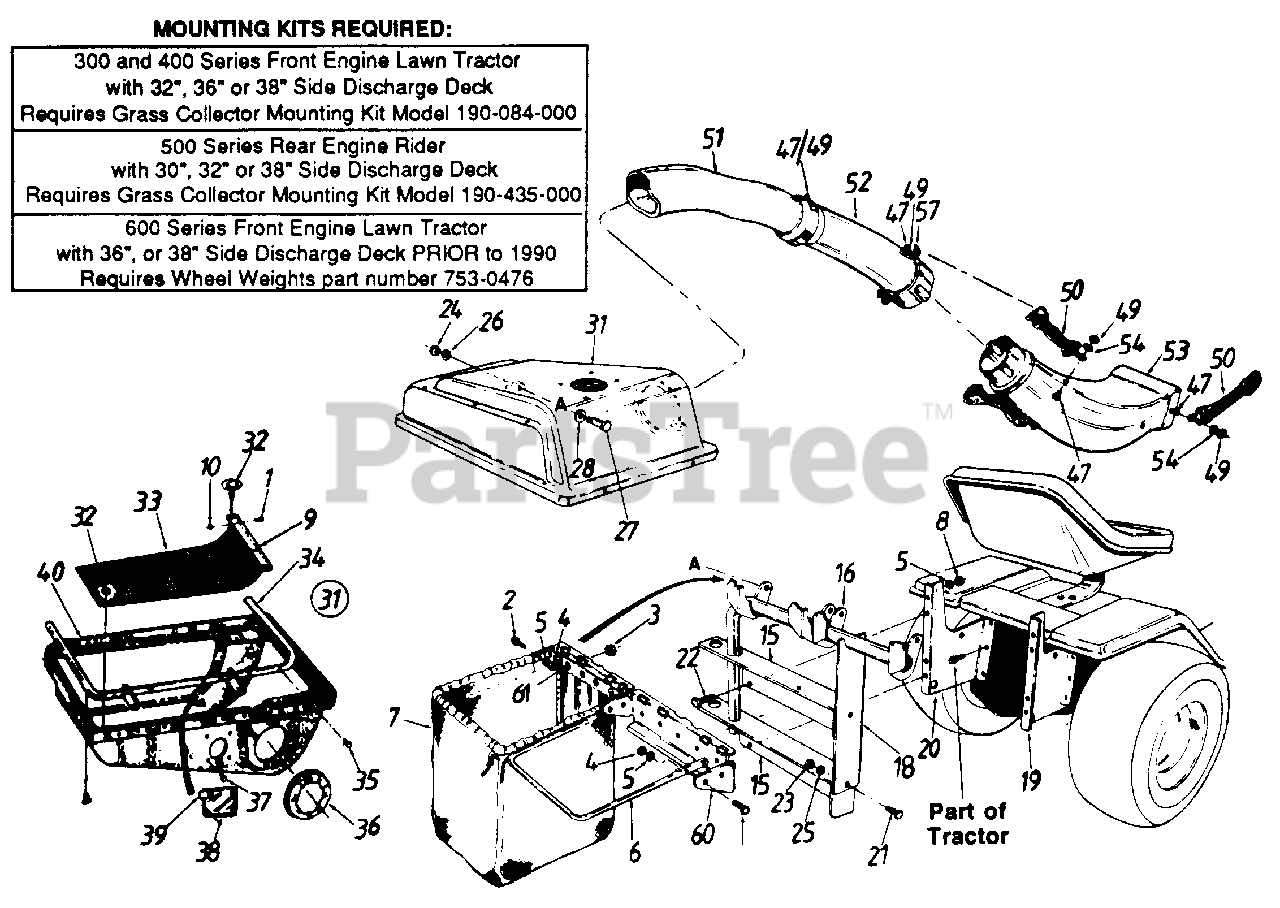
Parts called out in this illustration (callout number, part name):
1	Pop Rivet .188 Dia.
2	Hex Bolt 1/4-28 x .75"
3	Hex Sems Nut #10-24 Thd.
4	Hex Nut 1/428 Thd.
5	L-Wash. 1/4" I.D.
7	Grass Catcher Bag
8	Hex Nut 1/4-20 Thd.
9	Screen Mtg. Brkt.
10	Flat Wash. 1/4" I.D.
16	Catcher Support Tube Ass'y.
18	Catcher Latch and Support Brkt.
22	Hex Bolt 1/4-20 x .62" Lg. Grade 5
23	Hex Nut 5/16-18 Thd.
24	Hex Nut 3/8-16 Thd.
25	L-Wash. 5/16" I.D.
26	L-Wash. 3/8" I.D.
27	Shld. Bolt 3/8-16 x 50" Dia.
28	Bell-Wash. .505" I.D. x .0" O.D.
31	Grass Catcher Cover Ass'y.
32	Twist Fastener
33	Screen
35	Hex AB-Tap Scr. 1/4 x .62"
37	Truss Mach. B-Tap Scr. #10 x .5" Lg.
38	Plastic Plate
39	Speed Nut
40	Grass Catcher Cover
47	Hex Bolt 1/4-20 x .5"
49	Hex Ins. L-Nut 1/4-20 Thd.
50	Retainer Strap Ass'y.
51	Catcher Elbow
52	Catcher Tube
53	Discharge Chute
54	L-Wash. .27" I.D.
57	Retainer Hook Brkt.
61	Truss Mach. Scr. #10-24 x 5" Lg.
